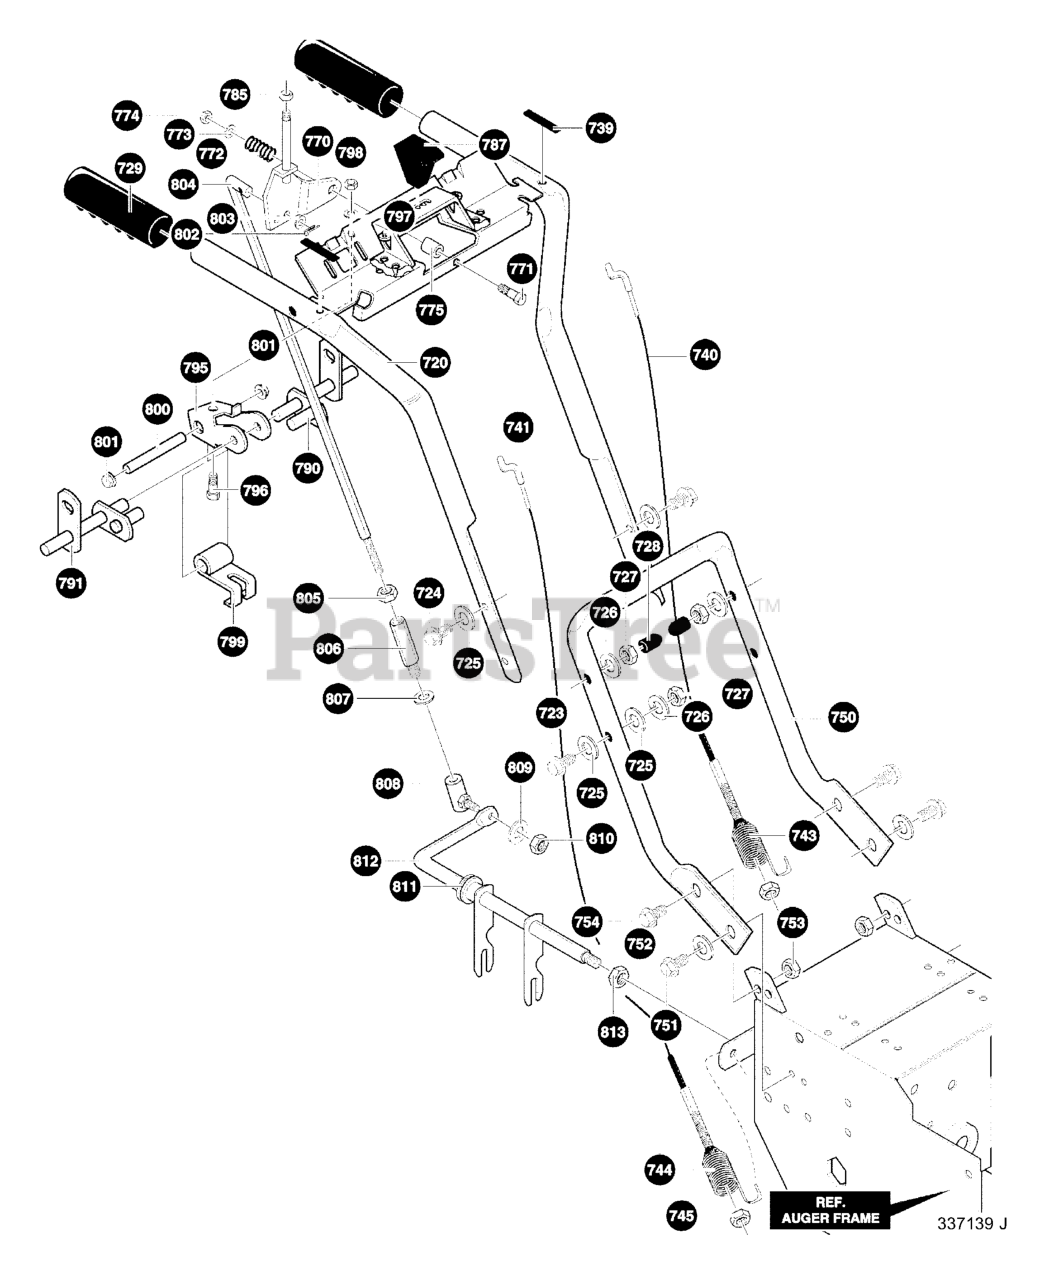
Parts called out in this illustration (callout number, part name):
720	HANDLE, ASSY
720	SUPPORT, ASSY HANDLE
723	SCREW, 3/8-16 x 2.00
724	SCREW, 3/8-16 x 3.00
725	WASHER, FLAT
726	WASHER, MDSPTLK
727	NUT, 3/8-16 REGHEX
728	STOP, PLASTIC
729	GRIP, HANDLE
739	BUMPER, RECT
740	CABLE, CLUTCH 32.19"
741	CABLE, AUG CLUTCH
743	TENSION SPRING
744	SPRING, AUGER CLUTCH
745	NUT, 1/4-20 HEX NYLOCK
750	HANDLE, LOWER
751	SCREW, 5/16-18 x 0.75
752	WASHER, SPTLK
753	NUT, 5/16-18
754	SCREW, 5/16-18 x 0.75
770	BRKT, SHIFT ACTUATOR
771	SCREW, 3/8-16 x 3.00
773	WASHER, FLAT
774	NUT, 3/8-16 HEXNYL
775	SPACER, SHIFT ACTUATOR
785	NUT, 1/4-20 REGHEX
787	KNOB, SHIFT 1/420
790	ROD, ASSY LH
791	ROD, ASSY RH
795	BRACKET, CAM RETAINER
796	SCREW, 5/16-18 x 0.75
797	WASHER, SPTLK
798	NUT, 5/16-18 REGHEX
799	CAM LOCK
800	PIN, SPRING PIVOT
801	NUT, PUSH ON
802	PIN, COTTER
803	FLATWASHER
804	ROD, SPEED CONTROL
805	NUT, 5/16-24 REGHEX
806	ADAPTOR, ROD SPEED
807	WASHER, SPTLK
808	JOINT, STEEL BALL
809	WASHER, SPTLK
810	NUT, 5/16-24 RGHEX
811	BEARING, FL
812	ROD, ASSY YOKE "PANEL"
813	NUT, 38-16 HEXCTRLK
